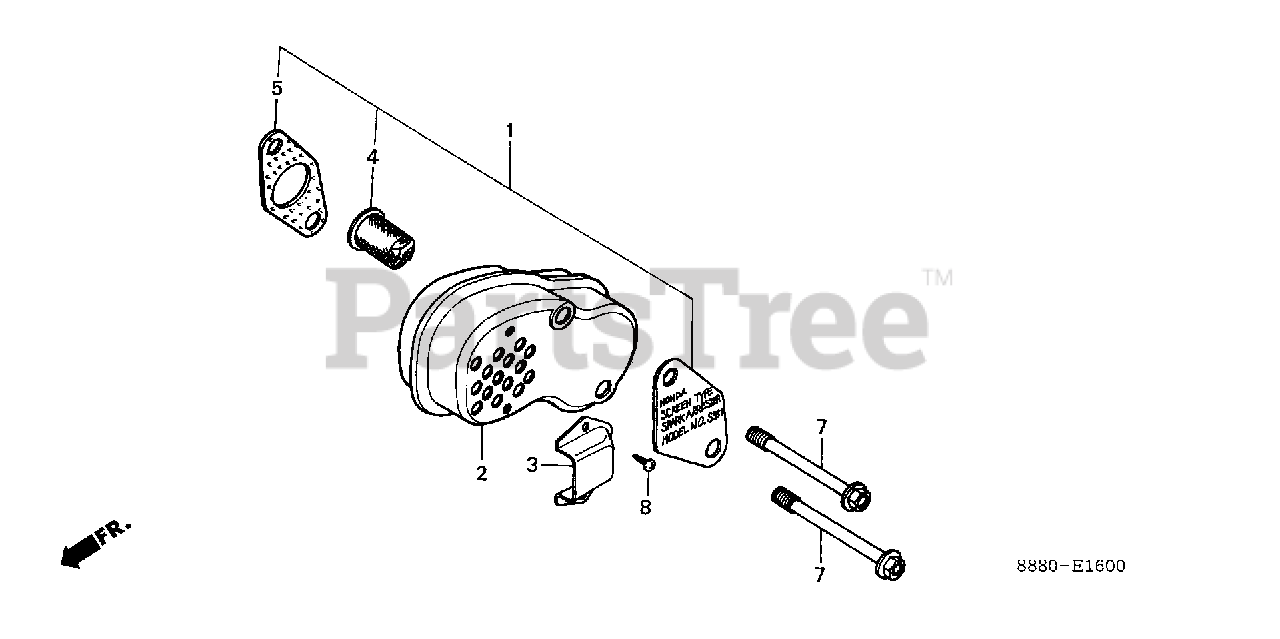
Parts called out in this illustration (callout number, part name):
1	ARRESTER KIT, SPARK
3	DEFLECTOR, MUFFLER
4	ARRESTER KIT, SPARK
5	GASKET, MUFFLER
7	BOLT, FLANGE (8X90) (NOT AVAILABLE)
8	SCREW, TAPPING (4X8) (NOT AVAILABLE)
